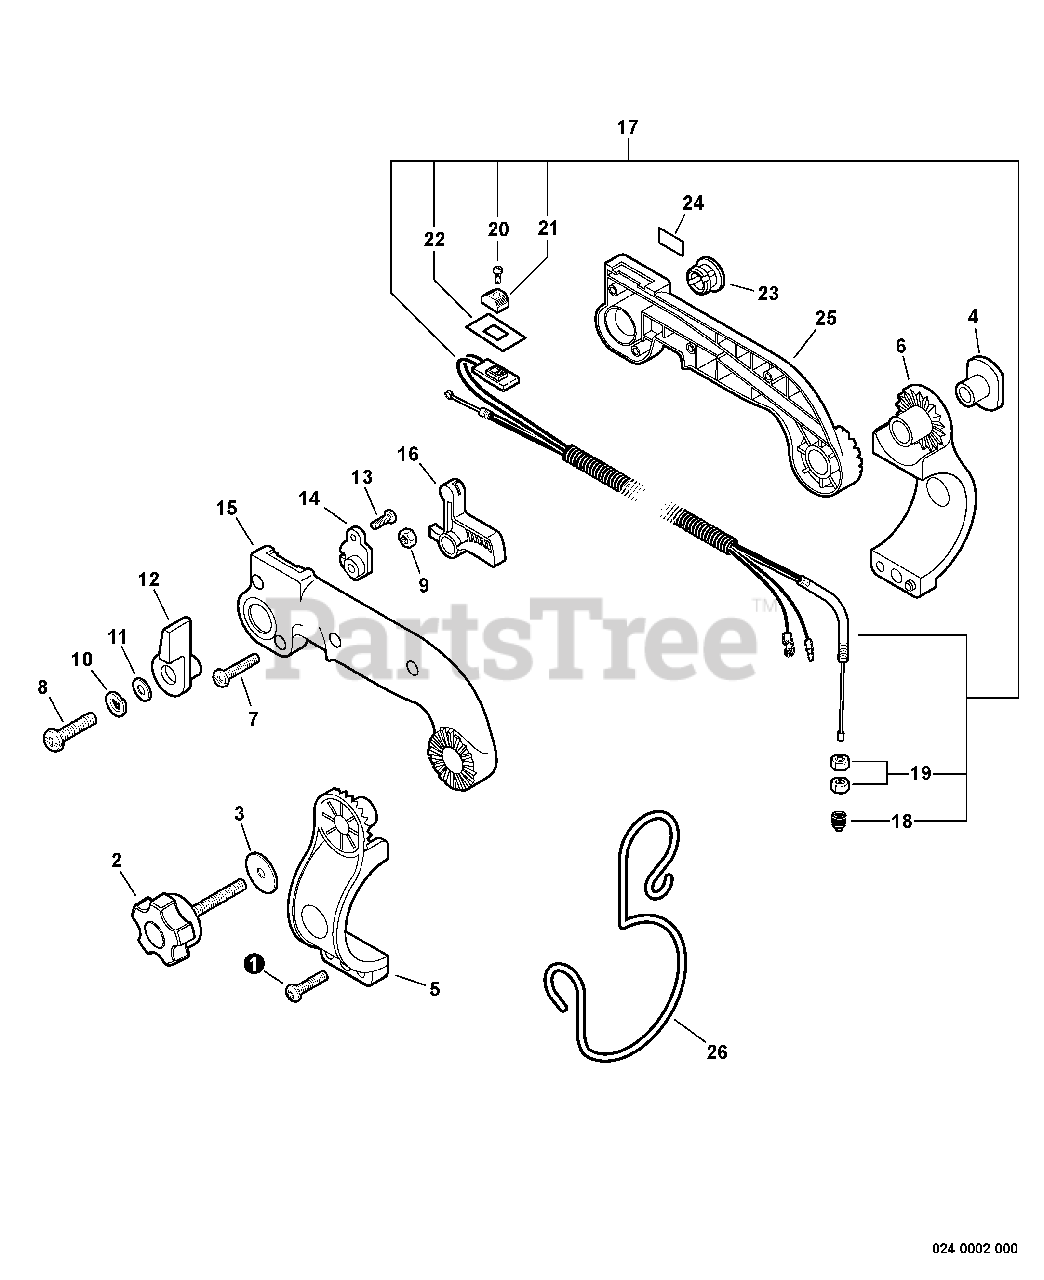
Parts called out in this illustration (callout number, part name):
1	SCREW, TAPPING 5×20
2	KNOB, SCREW
5	BRACKET, HANDLE - LEFT
6	BRACKET, HANDLE - RIGHT
7	SCREW TAPPING 5×20
8	SCREW 6×20
9	NUT, HEX M6
10	WASHER, SPRING 6
11	WASHER 6.5×13×1
12	CONTROL, THROTTLE
13	SCREW 4×10
14	BRACKET, THROTTLE
15	CONTROL HANDLE - LEFT
16	TRIGGER, THROTTLE
17	CABLE ASSY, CONTROL
18	CAP, DUST
19	NUT 6 MM
20	SCREW 3×10
21	KNOB, SWITCH - ORANGE
22	LABEL, SWITCH
24	LABEL, ON-OFF
25	CONTROL HANDLE - RIGHT
